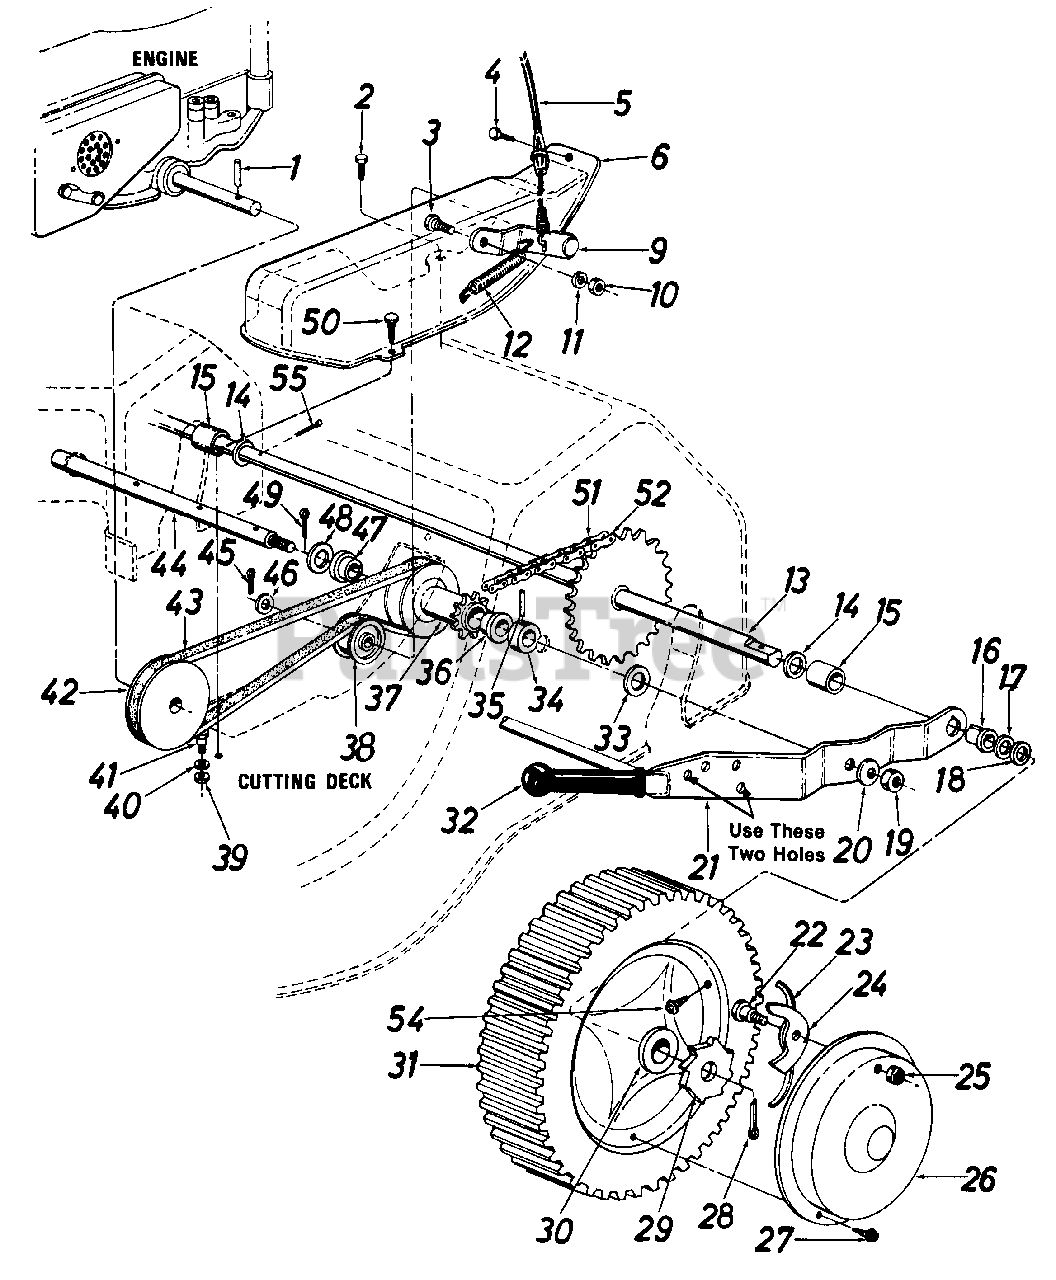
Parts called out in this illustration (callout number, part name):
1	Spring Pin Roll 3/16 Dia. x 1.50
2	Hex Wash. S. Tap Scr. 1/4-20 x .75" Lg.
3	Shld. Scr. .375 Dia. x .181
4	Hex Drilling Scr. #10 x .50" Lg.
5	Clutch Control Cable
6	Belt Cover
9	Idler Brkt. Ass'y.
10	Hex Nut 1/4-20 Thd.
11	L-Wash. 1/4" Scr.
12	Extension Spring .33 O.D. x 1.12 Lg.
13	Rear Shaft Ass'y.
14	Fl-Wash. .510 I.D. x 1.00 O.D.
15	Spacer .765 I.D. x .89 O.D. x .96" Lg.
16	Flange Brg. .506 I.D.
17	Fl-Wash. .531 I.D. x .93 O.D.
18	Fl-Wash. .531 I.D. x .93 O.D.
19	Hex Jam Nut 3/8-16 Thd.
20	Bell-Wash. .400 I.D. x .88 O.D. x .060
21	Rear Wheel Pivot Brkt. Ass'y.
22	Shld. Scr. .342 Dia. x .268
23	Spring Nylon
24	Pawl
25	Hex Ins. L-Nut 1/4-20 Thd.
26	Hub Cap
27	Pan Hd. Tap Scr. #12 x .50" Lg.
28	Cotter Pin 1/8 Dia. x 1.00" Lg.
30	Flange Bearing
31	Wheel Ass'y. Comp. - Rear
33	Bell-Wash. .400 I.D. x 1.13 O.D. x .040
34	Spacer .505 I.D. x .88 O.D. x .440
35	Spring Pin Roll 3/16 Dia. x 1.00" Lg.
36	Flange Brg. .506 I.D. - Plastic
37	Pulley w/9 Tooth Sprocket Ass'y.
38	Plastic Flat Idler
39	Hex Nut 5/16-18 Thd.
40	L-Wash. 5/16" Scr.
41	Shld. Scr. .437 Dia. x .350
42	Engine Pulley
43	"V"-Belt 1/2" x 33" Lg.
44	Pulley Shaft
45	Cotter Pin 1/8 Dia. x 1.00" Lg.
46	Fl-Wash. .531 I.D. x .930 x .050
47	Flange Brg. .506 I.D.
48	Fl-Wash. .531 I.D. x .930 x .050
49	Cotter Pin 3/32 Dia. x 1.00" Lg.
50	Hex Wash. Self-Tap Scr. 1/4-20 x .50" Lg.
51	#48 Chain 1/2" Pitch x 31 Links
52	#48 Master Link 1/2" Pitch
54	Hex Wash. Hd. Self-Tap Scr. Type "A" #8 x .50" Lg.
55	Cotter Pin 3/32" Dia. x 1.00" Lg.
